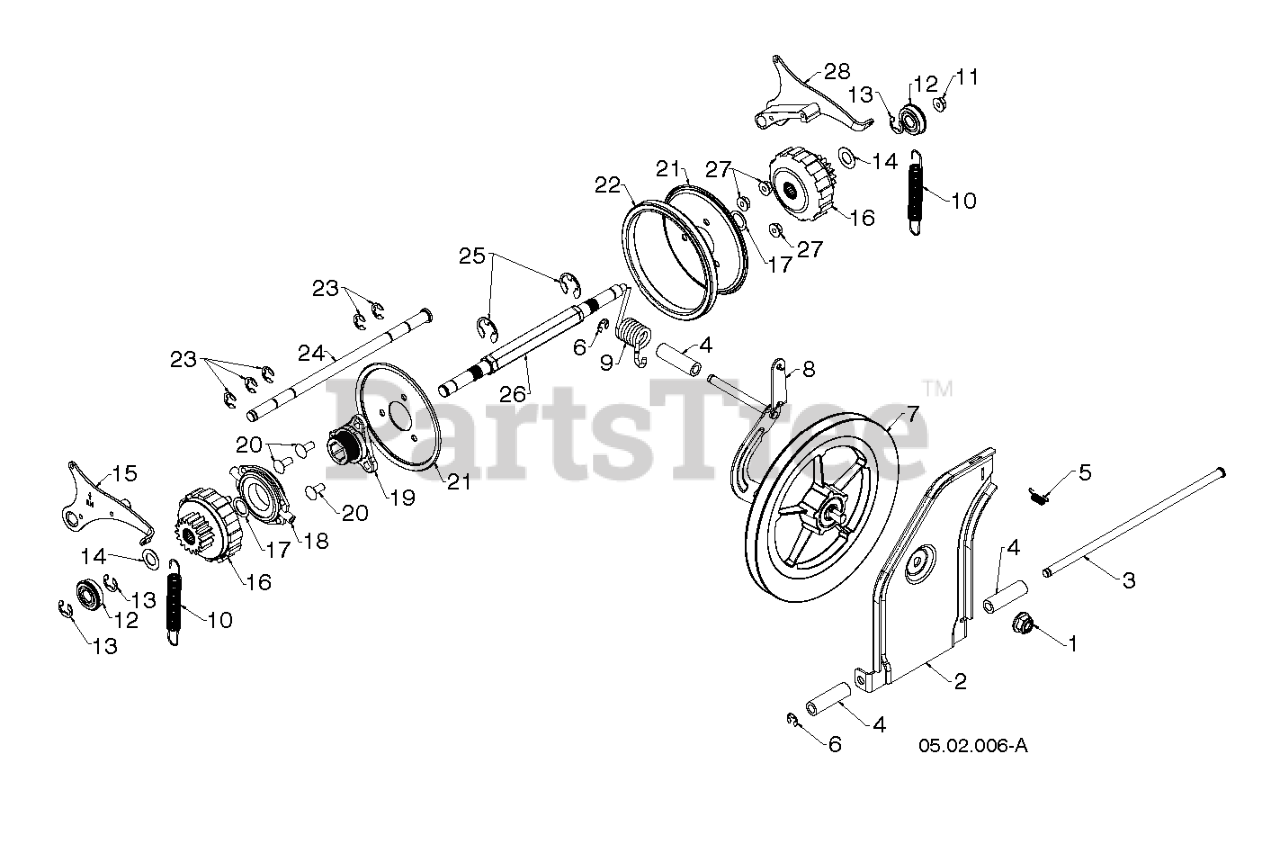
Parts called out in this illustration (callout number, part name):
1	NUT 1/2-13 HEX FLANGE NYLOK CL
3	ROD ROD,PIVOT, SWING PLATE ROD
4	SPACER YOKE, TORSION SPRING
5	SPRING LATCH
6	RETAINER RING E-RING CLEAR ZI
7	PULLEY ASSY TEXTURED TEXTURED
8	BRACKET.YOKE.ASSEMBLY.479
9	SPRING TORSION DRIVE
10	SPRING EXTENSION PS
11	NUT.HEX.FLANGE.LOCK.5/16-18
12	BEARING 9/16 ID. SNR
13	RING.RETAINING.1622-2RSNR.CLER
14	WASHER FLAT.637IDX1.00ODX21GA
15	PAWL.ASM.RH.SNOW
16	GEAR.ASM.PLANETARY
17	WASHER FLAT.59IDX1.065ODX25GA
18	BEARING HOUSING ASSY TRUNNION
19	HUB.RUBBER.WHEEL
20	RHSNB 5/16-18 X 3/4 GR5 BLK ZN
21	PLATE.RUBBER.WHEEL.BLACK
22	Friction Drive
23	CLIP E-RING_.500 SHAFT
24	ROD ROD, PAWL ROD
26	SHAFT SHAFT, PWR STR SHAFT
27	NUT.HEX.FLANGE.LOCK.5/16-18
28	PAWL.ASM.LH.SNOW
